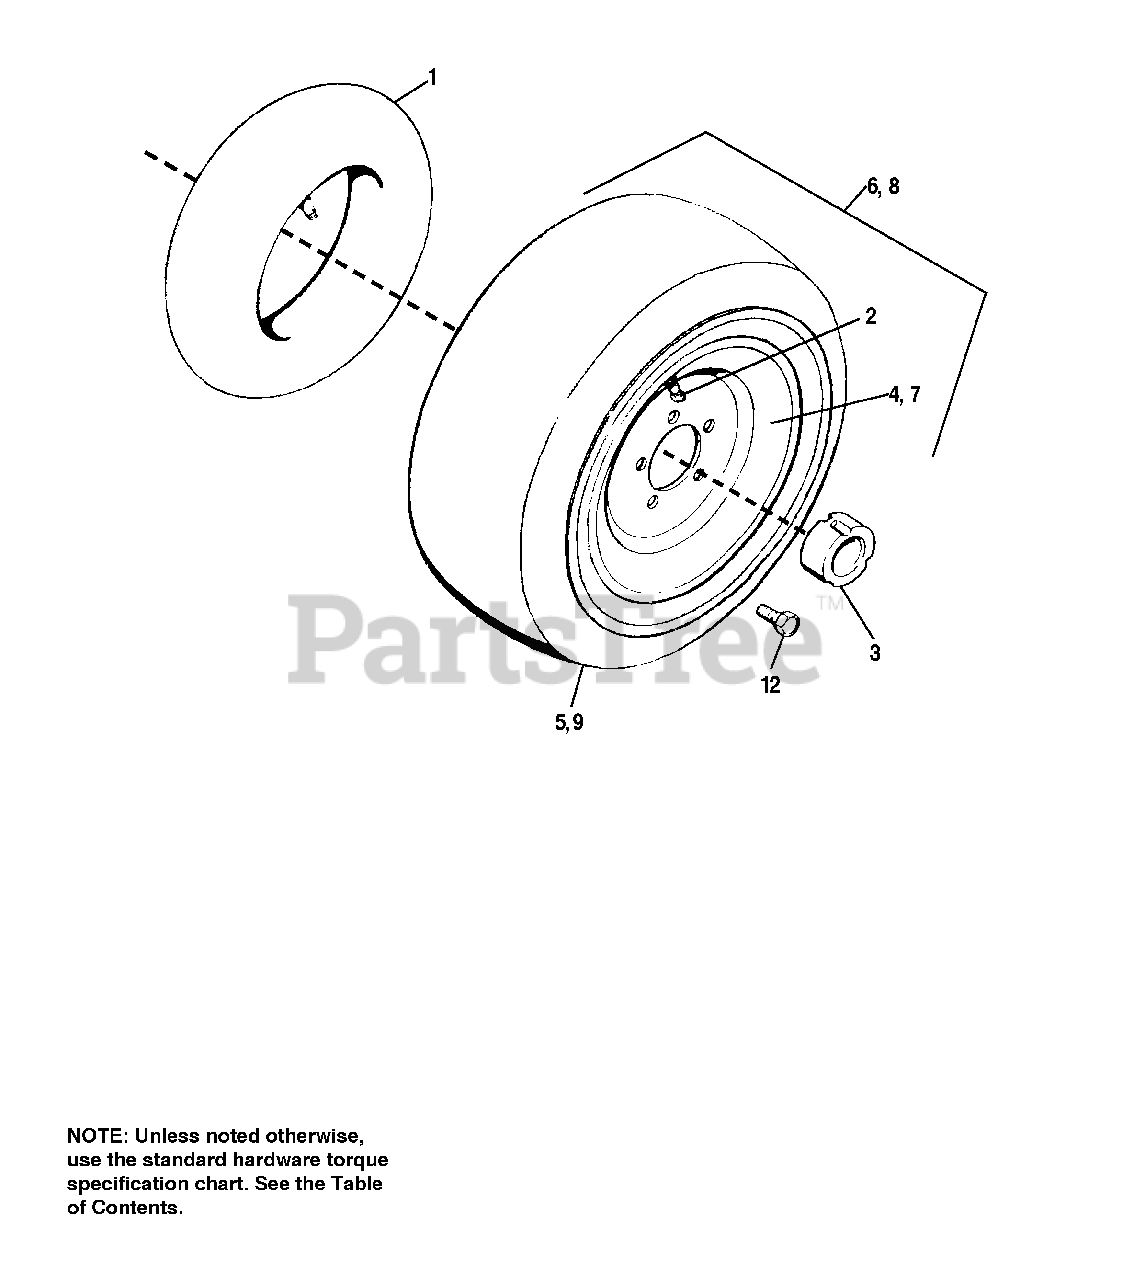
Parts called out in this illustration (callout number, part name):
2	VALVE STEM & CAP
4	REAR WHEEL, 24", Metallic Gray
5	TIRE, Turf, 23 x 10.5-12 (Dico)
6	REAR WHEEL & TIRE ASSY., Metallic Gray, 23 x 10.5-12
7	REAR WHEEL, 23", Metallic Gray
8	REAR WHEEL & TIRE ASSY., Metallic Gray, 24 x 13.00-12
9	TIRE, Turf, 24 x 13.00-12, Tubeless (Dico)
